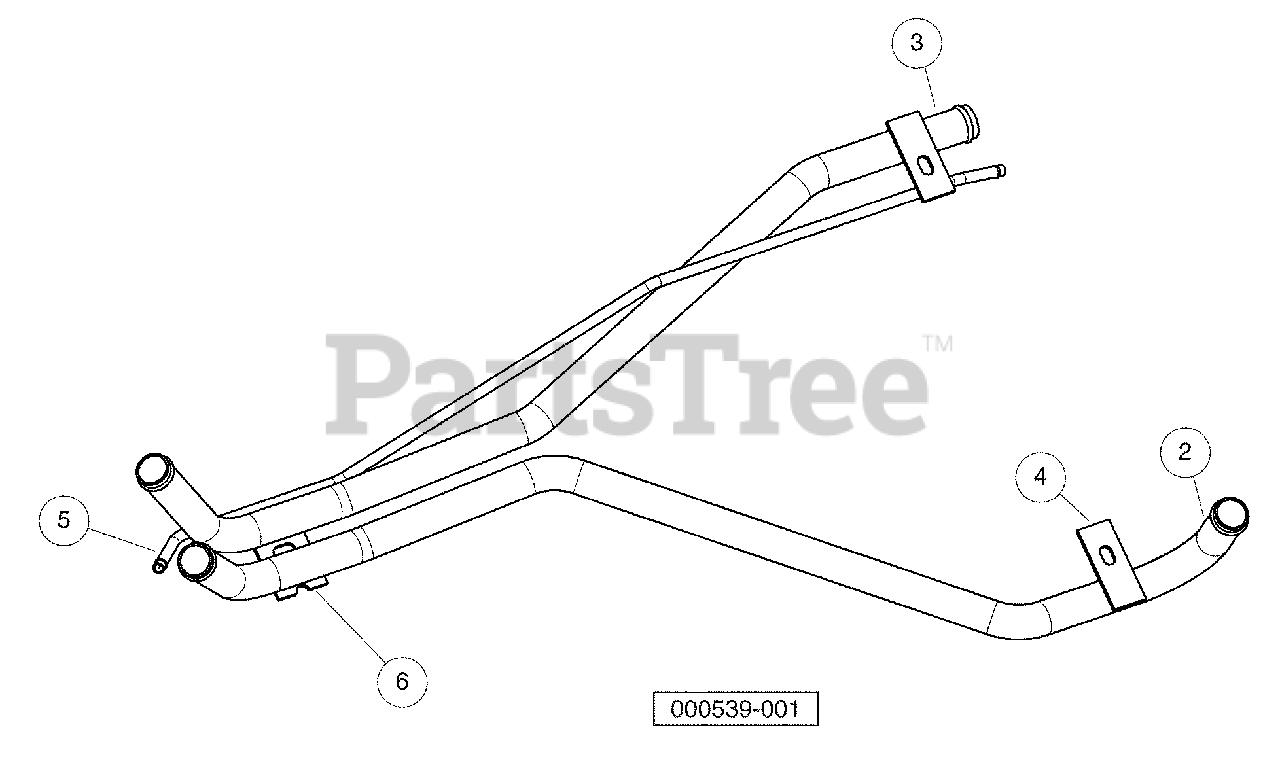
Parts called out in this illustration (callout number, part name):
1	Weldment, Group, Coolant Pipe
2	Pipe, Coolant Upper
3	Pipe, Coolant Lower
4	Tab, Rear Mntg, Coolant Pipe
5	Pipe, Vent, Coolant
6	Tab, Cooling Pipe Mount
